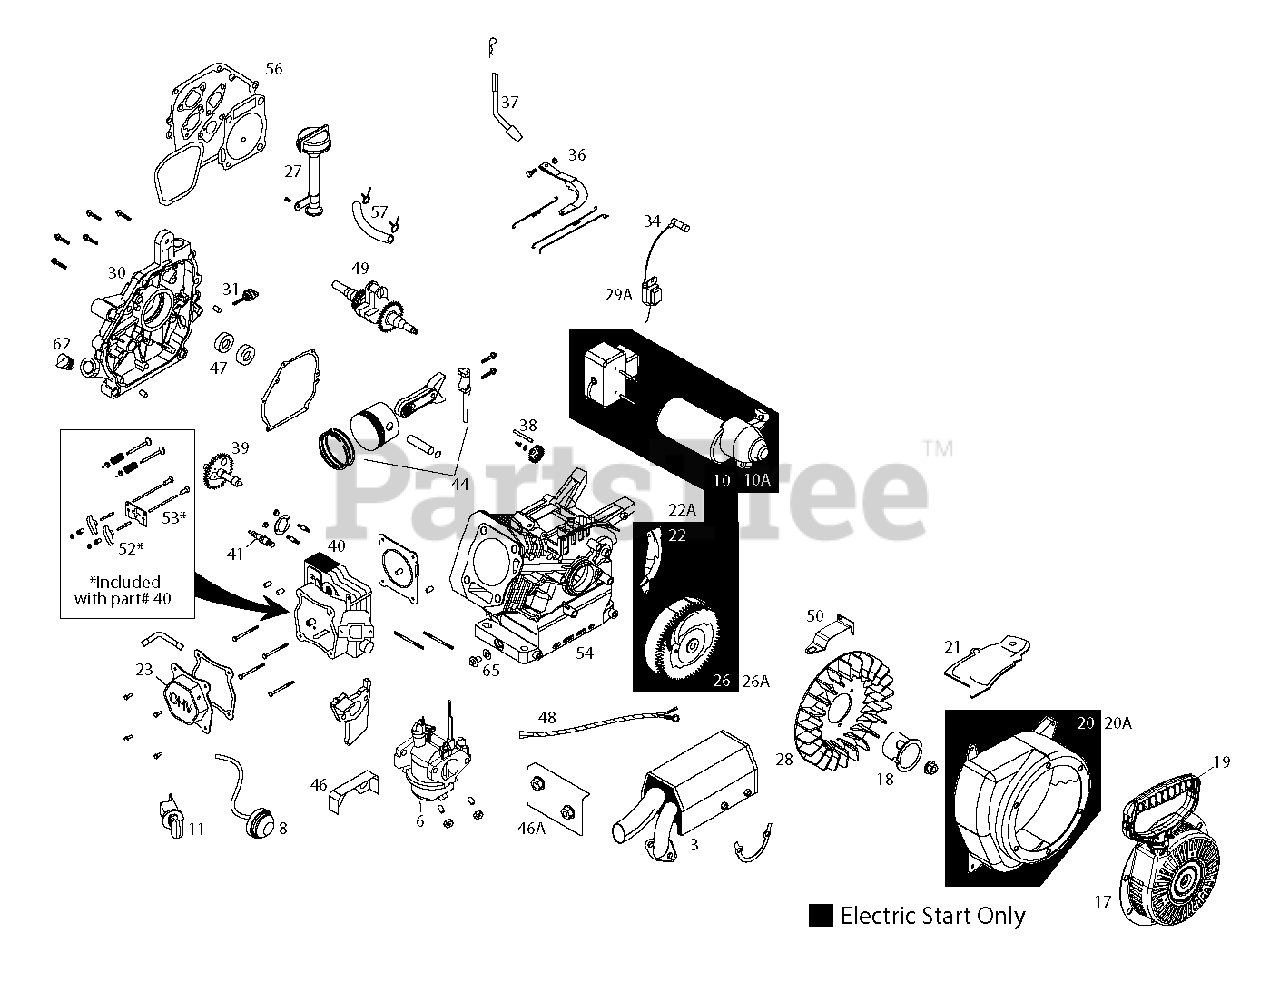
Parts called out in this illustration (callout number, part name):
3	MUFFLER.ASM.LCT.208CC.SS
6	CARB.ASM.SS/SNO.LCT(SKSNO313)
8	BULB.FUEL.PRMR.W/HOSE(SKSNO306
10	STARTER.ASM.ELEC.(SKSNO411)
11	SWITH.KEY.ASSEM.SNOW.SINGLE.ST
17	RECOIL.STRT.ROUND(BLK) SNOW
18	STRTER.CUP(NON-SLOT)SKSN0601.2
19	STARTER.GRIP.SNOW.LCT.SKSN0603
20	BLOW.HSG.ASSY.ELEC(SKSN-0602)
20A	BLOW.HSG.ASSY.ELEC(SKSN-0612)
21	SHILED.FLYWEEL.SYS(SKSN-0604)
22	SHLD.ELEC.START.FLY(SKSN-0605)
22A	SHIELD.FLYWEEL.MAN(SKSN-0607)
23	VALVE COVER ASSEMBLY
26	FLYWHL.ASSY.ELECT.(SKSN0405)
26A	RP KIT.FLYWHEEL.SERVICE
27	HIGH OIL-FILL TUBE ASSY
28	KIT.COOLNG.FAN.SERV(SK208-4000
29A	208CC IGN COIL (STD)
30	CRANKCASE COVER ASSY
31	DIPSTICK SMALL
34	SPARK.PLUG.BOOT.SNW,SKSN4691.1
36	KIT.GOVERNOR.ARM(SUMMER ENG)
37	KIT.GOVERNOR.CRANK(SK208-3100)
38	GOVENOR.GEARS ASM(SK2082900)
39	KIT.CAMSHAFT.SRV(SK208-1600)
40	CYLINDR.HEAD.SRV.KIT
41	SPARK.PLUG(2083810)
44	KIT.PISTON.SRV(SK208-1400)
46	SHIELD.VAPOR.SNOW
46A	SHIELD.INTAKE.(LCT.SKSN0140.1)
47	SEAL KIT (2 PCS)
48	HARNESS WIRE/WCDI IGN.SKSNO145
49	CRANKSHAFT-KEYED(SK2081800.1)
50	SPEED.CTRL.BRKT.(SKSN0150)
52	ROCKER ARM KIT
53	KIT.PUSH.ROD.SRV(SK208-1001)
54	CYLINDER.ASM.SKSN0001.2
56	GASKET.KIT.208CC(SK2084300.1)
57	KIT.FUEL.HOSE.208CC.SING/STAGE
62	NON REMOVABLE PLUG
65	KIT.OIL.DRAIN.PLUG(SK2089911
